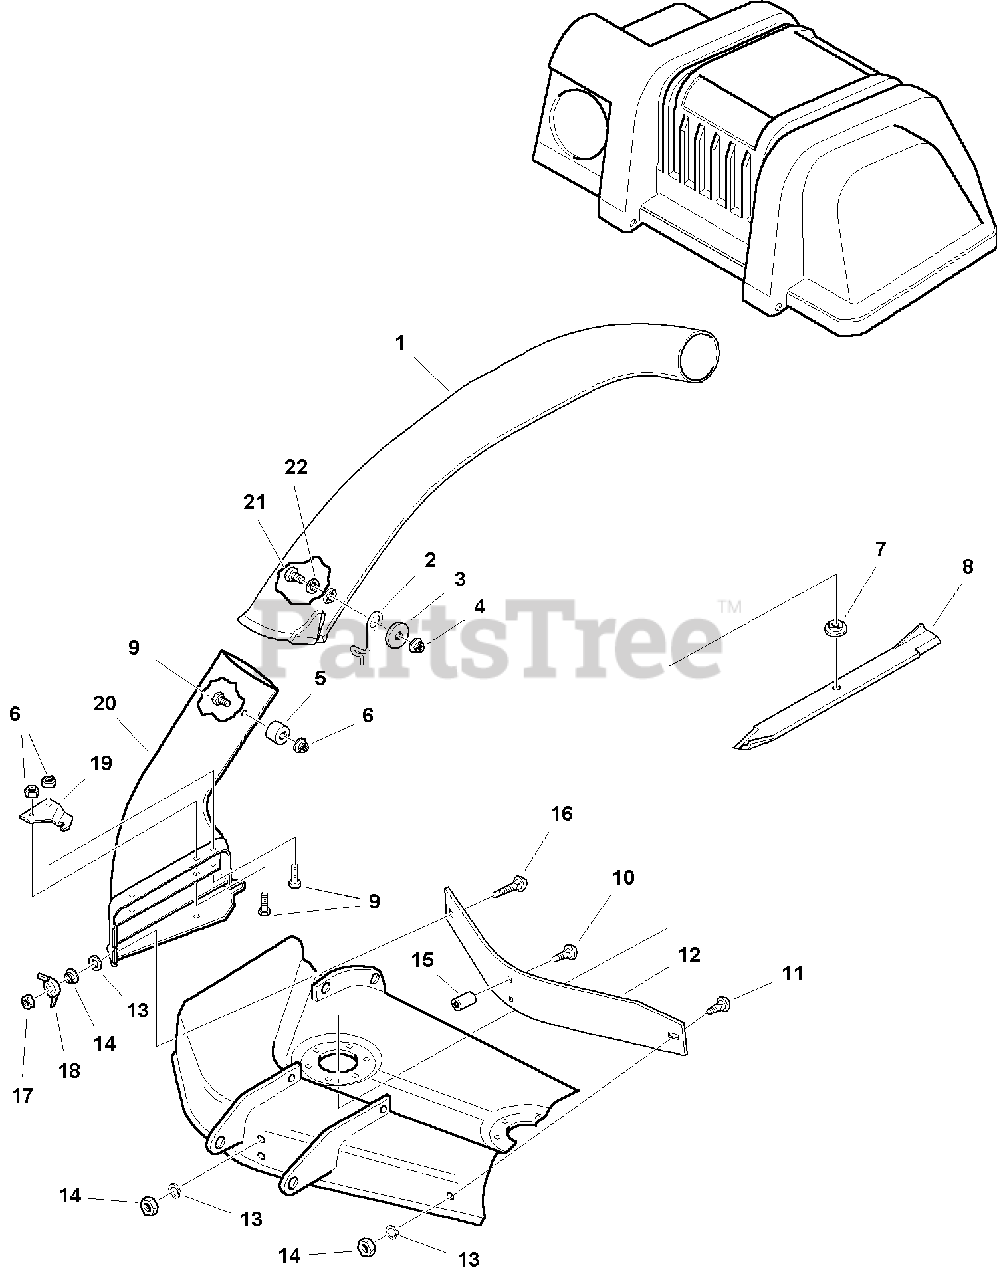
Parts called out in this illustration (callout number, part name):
1	TUBE, Transfer
2	LATCH, Tube
3	WASHER, Flat, 5/16
4	NUT, Flange Lock, 5/16-18
5	WASHER, Special
6	NUT, Esna, Hex Lock, 5/16-18
7	ADAPTER, Blade, High Lift
8	BLADE, High Lift, 38" Mower
9	CAPSCREW, Hex Head, 5/16-18 x 3/4
10	CARRIAGE BOLT, 5/16-18 x 1-3/4
11	CARRIAGE BOLT, 5/16-16 x 5/8
12	BAFFLE, 38" Mower
13	LOCKWASHER, 5/16
14	NUT, Hex, 5/16-18
16	CARRIAGE BOLT, 5/16-18 x 2-1/4
17	NUT, Hex Centerlock, 5/16-18
18	WING NUT ASSEMBLY
20	ADAPTER
21	CAPSCREW, Hex Head, 5/16-18 x 3/4
22	WASHER, 5/16
